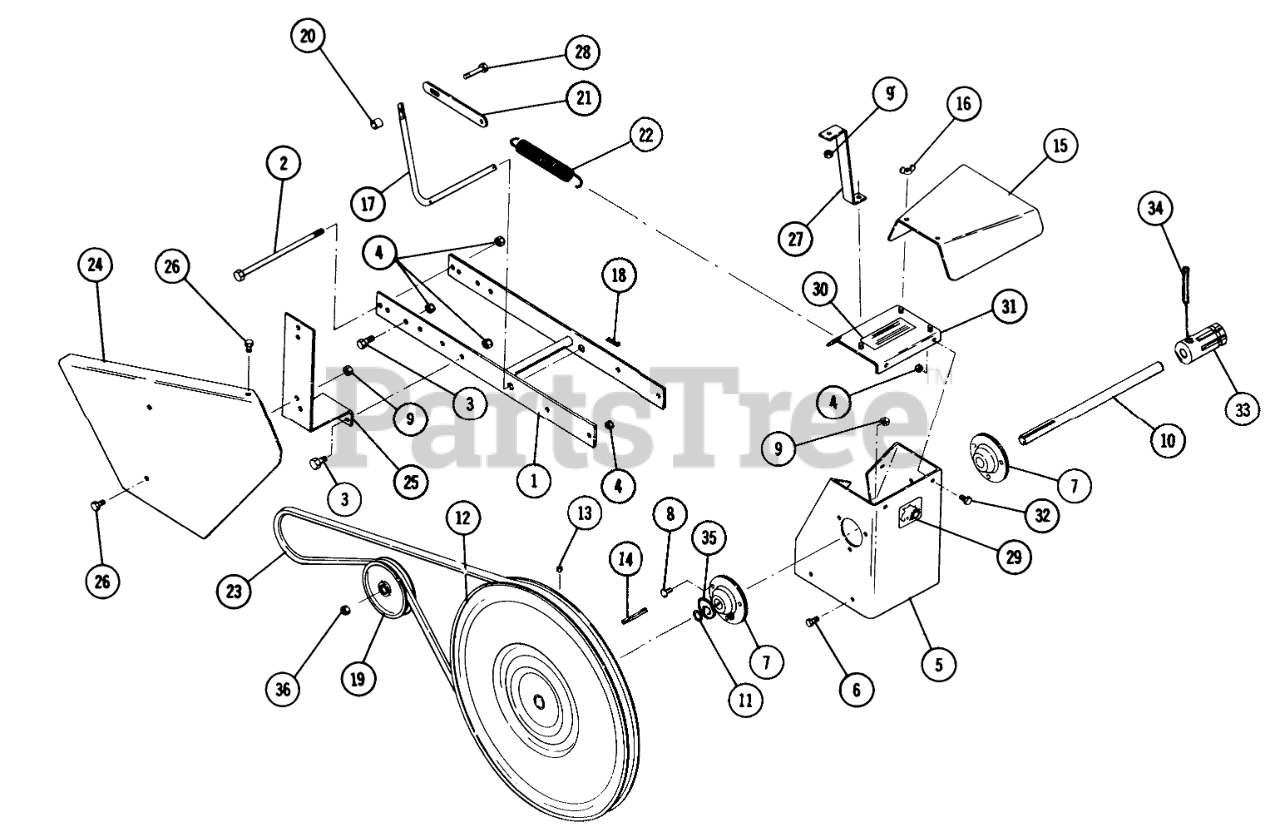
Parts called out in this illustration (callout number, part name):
1	Ass-y Frame
2	Bolt Hex Head 3/-16 x 8 1/2
3	Bolt 3/8-16 x 1
4	3/8-16 E.S.
5	Shroud
6	Bolt 3/8-16 x 1
7	Bearing
8	Bolt Hex 5/16-18 x 3/4
9	Nut 5/16-18
10	Ass-y Shaft-Spline
11	RING-SNAP, EXTERNAL
12	Pulley
13	Set Screw, 5/16-18 x 5/16
14	KEY-STRAIGHT
15	Shield
16	Nut-Wing Elastic Stop
17	Rod-Pulley
18	Hairpin
19	Pulley-Idler
20	Spacer
21	Link
22	SPRING R
23	V-BELT
24	Belt-Guard
25	Bracket
26	Bolt 5/16-18 x
27	Brace-Belt Guard
28	Bolt, 3/8 16 x 2
29	Decal
30	Decal-Caution
31	Ass-y Cover
32	Bolt 3/8-16 x 3/4
33	31109 '59 17 SNWHOU
34	Spirol Pin
35	WASHER
